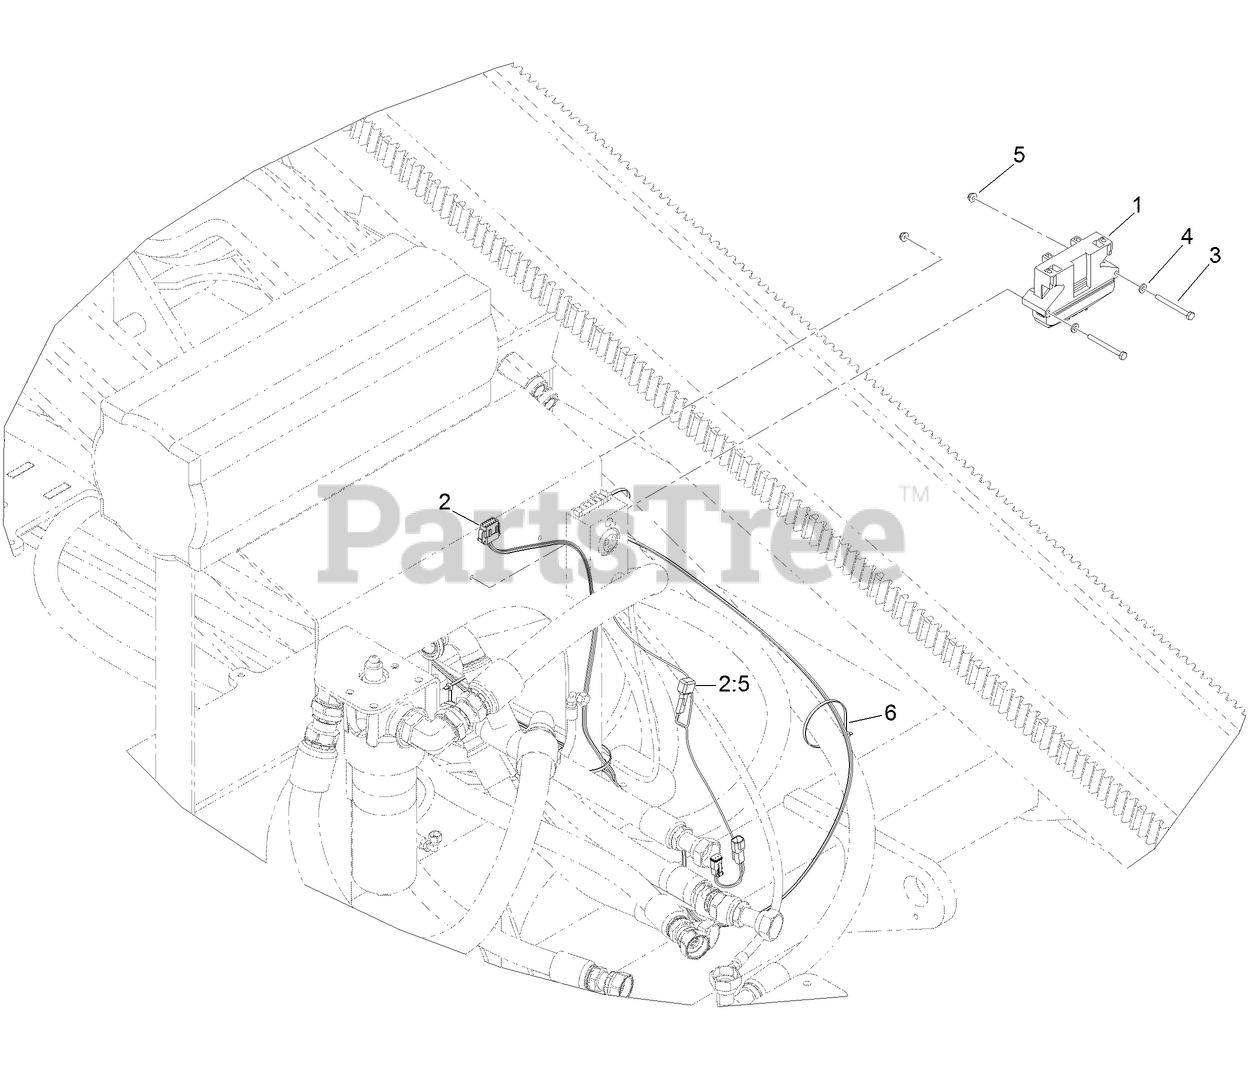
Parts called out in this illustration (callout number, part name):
1	MICROPROCESSOR
2	HARNESS-WIRE
3	SCREW-HH
4	WASHER-FLAT
5	NUT-HF
6	TIE-CABLE
